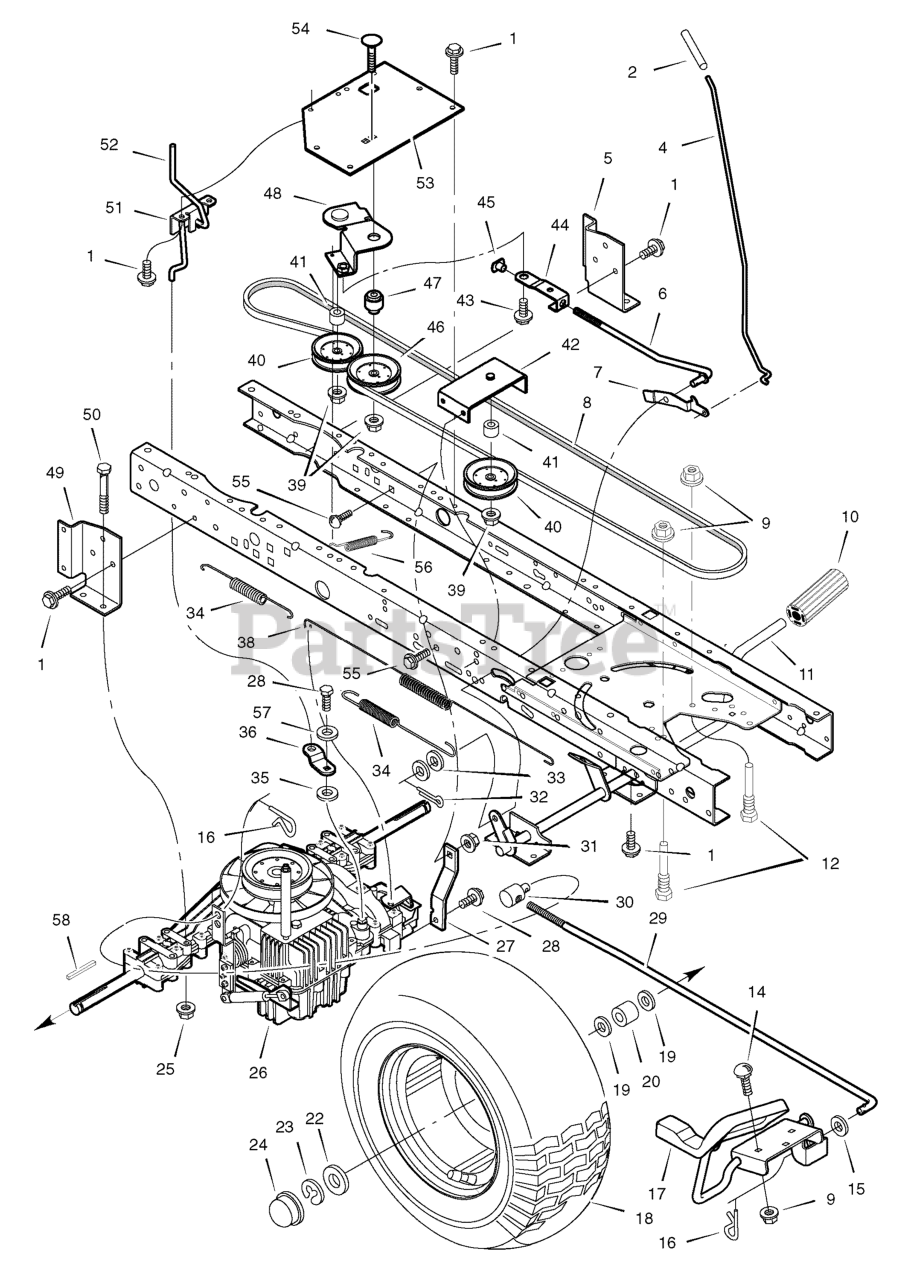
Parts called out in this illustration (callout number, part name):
2	Grip, Parking Brake
4	Rod, Parking Brake
5	Bracket, Left Transaxle
6	Rod, Clutch
7	Latch, Parking Brake
8	V-Belt, Drive
9	Nut, Flange
10	Pedal, Brake/Clutch
11	Assembly, Brake Pedal
12	Screw, Guide
14	Bolt, Carriage
16	Pin, Hair
17	Pedal Assembly, Hydro
18	Wheel & Tire Assembly, Rear
24	Cap, Hub
25	Nut, Centerlock
26	Transaxle, Peerless Hydro **
27	Strap, Torque
29	Rod, Control
30	Nut, Adjusting
31	Nut, Centerlock
32	Pin, Cotter
34	Spring, Extension
36	Arm, Disconnect
38	Spring, Brake
39	Locknut, Flange
40	Pulley, Idler
42	Bracket, Idler Assembly
43	Bolt, Shoulder
44	Link, Clutch
45	Nut, Tee
46	Pulley, Idler
47	Bushing, Pivot
48	Arm Assembly, Idler
49	Bracket, Right Transaxle
50	Bolt, Hex
51	Bracket, Dump Valve
52	Rod, Roll Release
53	Bracket, Idler Pivot
54	Bolt, Carriage
55	Bolt, Carriage
56	Spring, Clutch
58	Key, Square 3/16"
